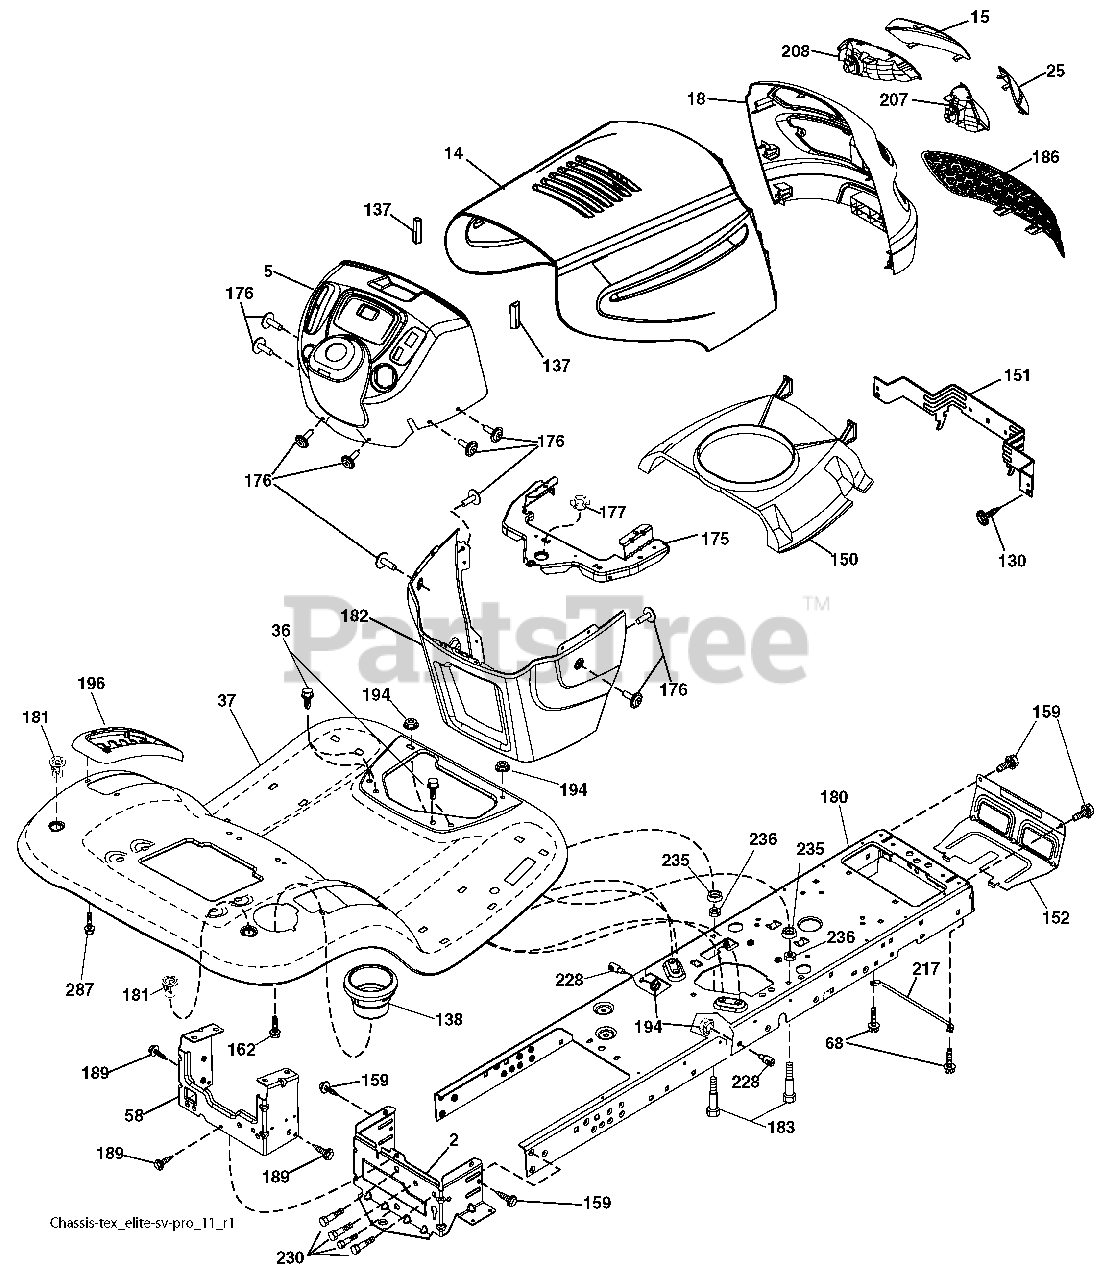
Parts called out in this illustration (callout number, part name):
2	Drawbar Lower
5	Dash
14	Hood
15	Lens Grille LH
18	Grille
25	Lens Grille RH
36	Screw 5/16-18 x 3/4
37	Fender
58	Drawbar Upper
68	Screw Thdrol 5/16-18 x 1/2
130	Screw #10 x 0.750
137	Bumper Hood
138	Cupholder
150	Duct Heat Hood
151	Bracket Pivot
152	Shield Browning/Debris
159	Screw Hexwsh Thdrol 3/8-16 x 3/4
162	Screw Hex Wsh Hi-Lo 1/4 x 1/2
175	Crossmember
176	Screw 10-24 x 5/8 Wshd Qdrx
177	Bushing Steering
181	Bushing Mtg. Fender Crgo.
182	Dash Lower
183	Bolt Fin Hex 5/16-18 x 1-1/4
189	Screw 5/16-18 x 3/4
194	Nut Lock Hex Flange 5/16-18
196	Console Asm. Deck Lift
207	Bezel Grille RH
208	Bezel Grille LH
217	Rod Pivot Hood
228	Stud Fastener
230	Bolt Shoulder 5/16-18
235	Spacer Fender
236	Nut Center Lock 5/16-18
287	Screw 1/4-20 x 3/8
